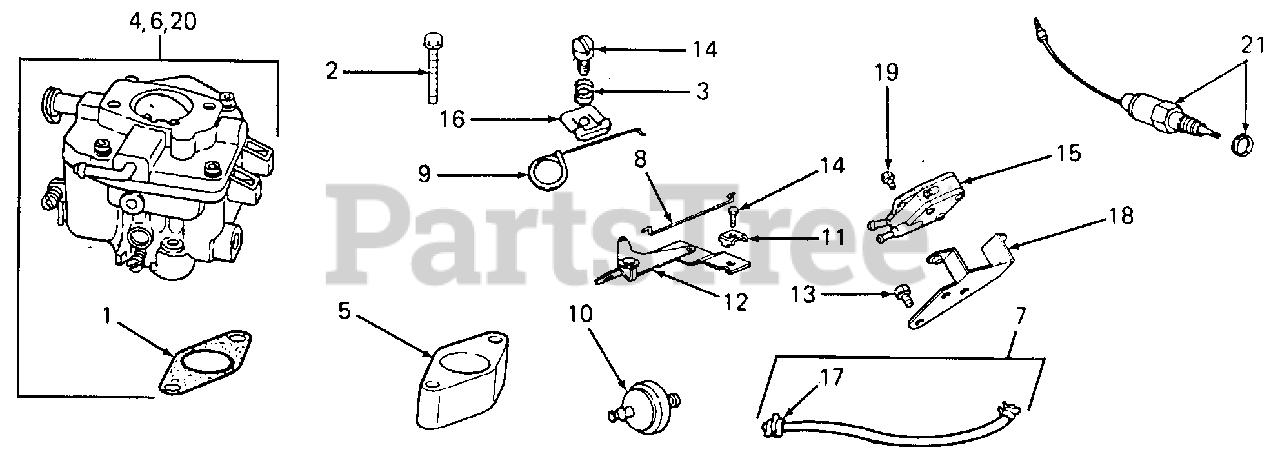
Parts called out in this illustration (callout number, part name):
1	Gasket, Carburetor Mtg
2	Screw, Sems
3	Spring, Lever
4	Kit, Carburetor Repair
5	Spacer, Carburetor
6	Carburetor Assy
7	Line, Fuel
8	Link, Choke
9	Rod, Manual Control
10	Filter, Fuel
11	Clamp, Casing
12	Bracket, Choke
13	Screw, Sems
14	Screw, Hex Hd
15	Pump, Fuel
16	Cup, Friction
17	Clamp, Fuel Line
18	Bracket, Fuel Pump
19	Screw, Mtg
20	Gasket Set, Carburetor
21	Solenoid
